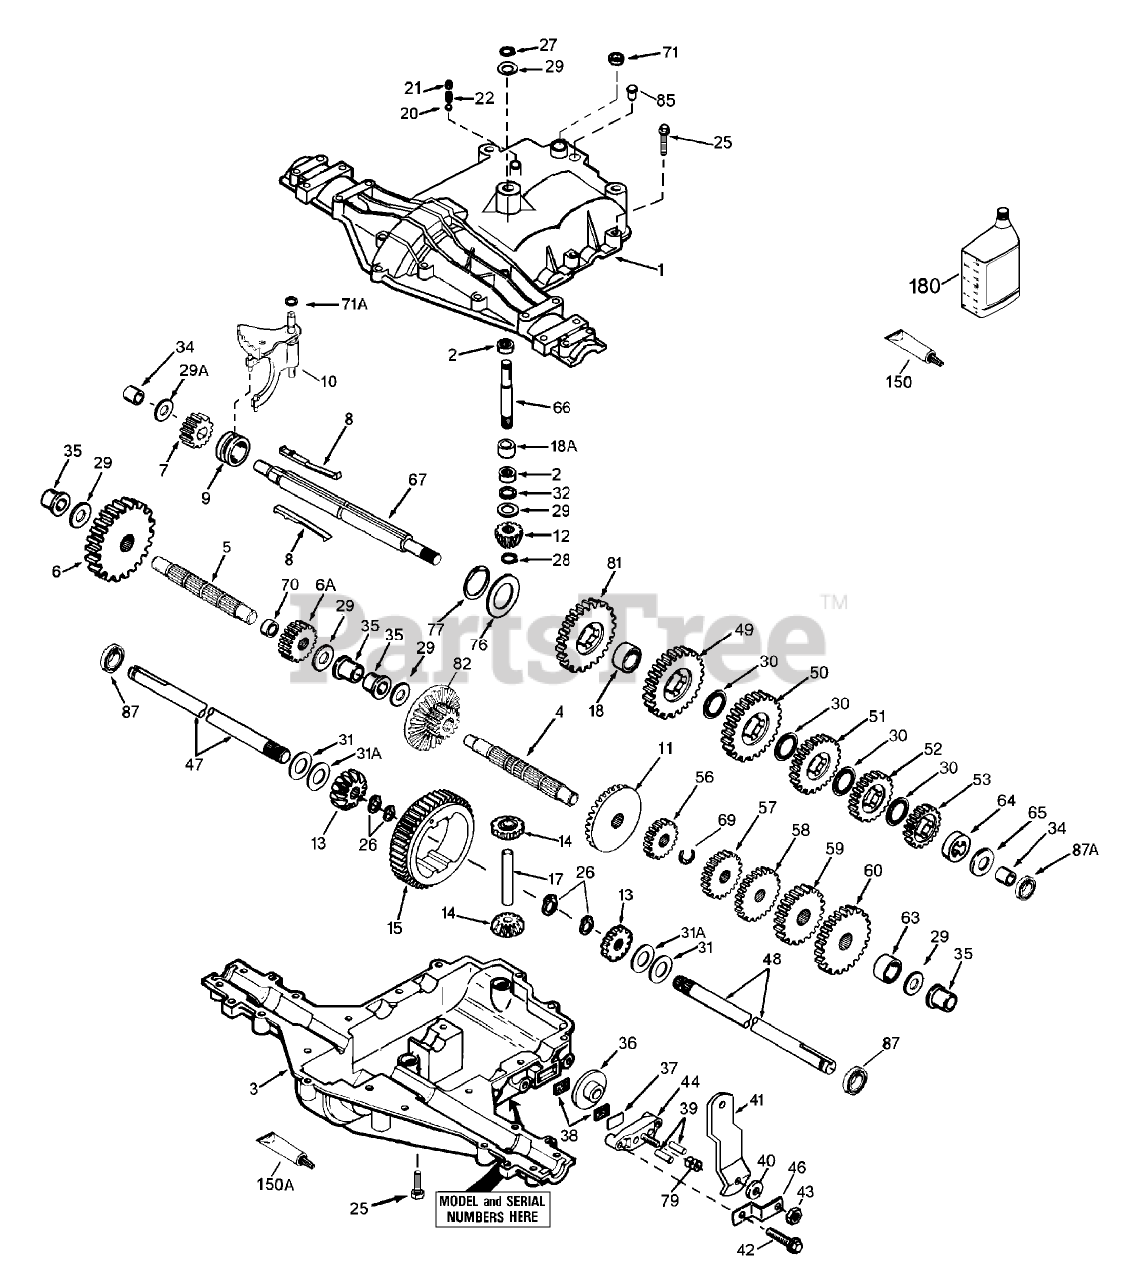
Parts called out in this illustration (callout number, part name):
1	Transaxle Cover
2	Bearing-Needle
3	Transaxle Case
4	Countershaft
5	Output Shaft
6	Spur Gear (38 teeth)
6A	Spur Gear (15 teeth-steel)
7	Spur Gear (11 teeth-steel)
8	Shift Key
9	Shift Collar
10	Shift Rod Fork
11	Bevel Gear (30 teeth)
12	Input Bevel Pinion (13 teeth)
13	Bevel Gear (16 teeth-steel)(Incl. 13)
14	Bevel Gear (16 teeth-steel)(Incl. 13)
15	Ring Gear (43 teeth)
17	Drive Pin
18	Spacer
18A	Spacer
20	Ball-Steel
21	Screw-Set
22	Spring
25	Ring Set (.020 O S)
26	Retaining Ring (pkg of 2)
27	Ring-Snap
28	Ring-Retainer
29	Washer
29A	Washer
30	Washer
31	Washer
31A	Flat Washer (.062 wide)
32	Oil Seal
34	Bushing
35	Flanged Bushing
36	Brake Disk
37	Brake Pad Plate
38	Pad-Brake 2/Pkg
39	Dowel Pin
40	Washer
41	Brake Lever
42	Ring Set (.020 O S)
43	Locknut
44	Nozzle-Carburetor
46	Bracket
47	Axle (11-15/16" long)
48	Axle (16-1/2" long)
49	Spur Gear (29 teeth-steel)
50	Spur Gear (23 teeth-steel)
51	Spur Gear (20 teeth)
52	Spur Gear (16 teeth-steel)
53	Spur Gear (15 teeth-steel)
56	Spur Gear (11 teeth-steel)
57	Spur Gear (17 teeth-steel)
58	Spur Gear (20 teeth)
59	Spur Gear (24 teeth-steel)
60	Spur Gear (25 teeth)
63	Spacer
64	Spacer
65	Washer
66	Input Shaft
67	Shifter Brake Shaft
69	Retaining Ring
70	Spacer
71	Cut Seal-Square
71A	O Ring
76	Washer
77	Inverted Retaining Ring
79	Piston ASM (.020 O S)
81	Spur Gear (27 Teeth)
82	Bevel Spur Gear (30 13 teeth)
85	Pipe Plug
87	Oil Seal
87A	Oil Seal
150	Liquid Gasket RTV Silicone
150A	Liquid Gasket Loctite #242
180	Gear Oil
